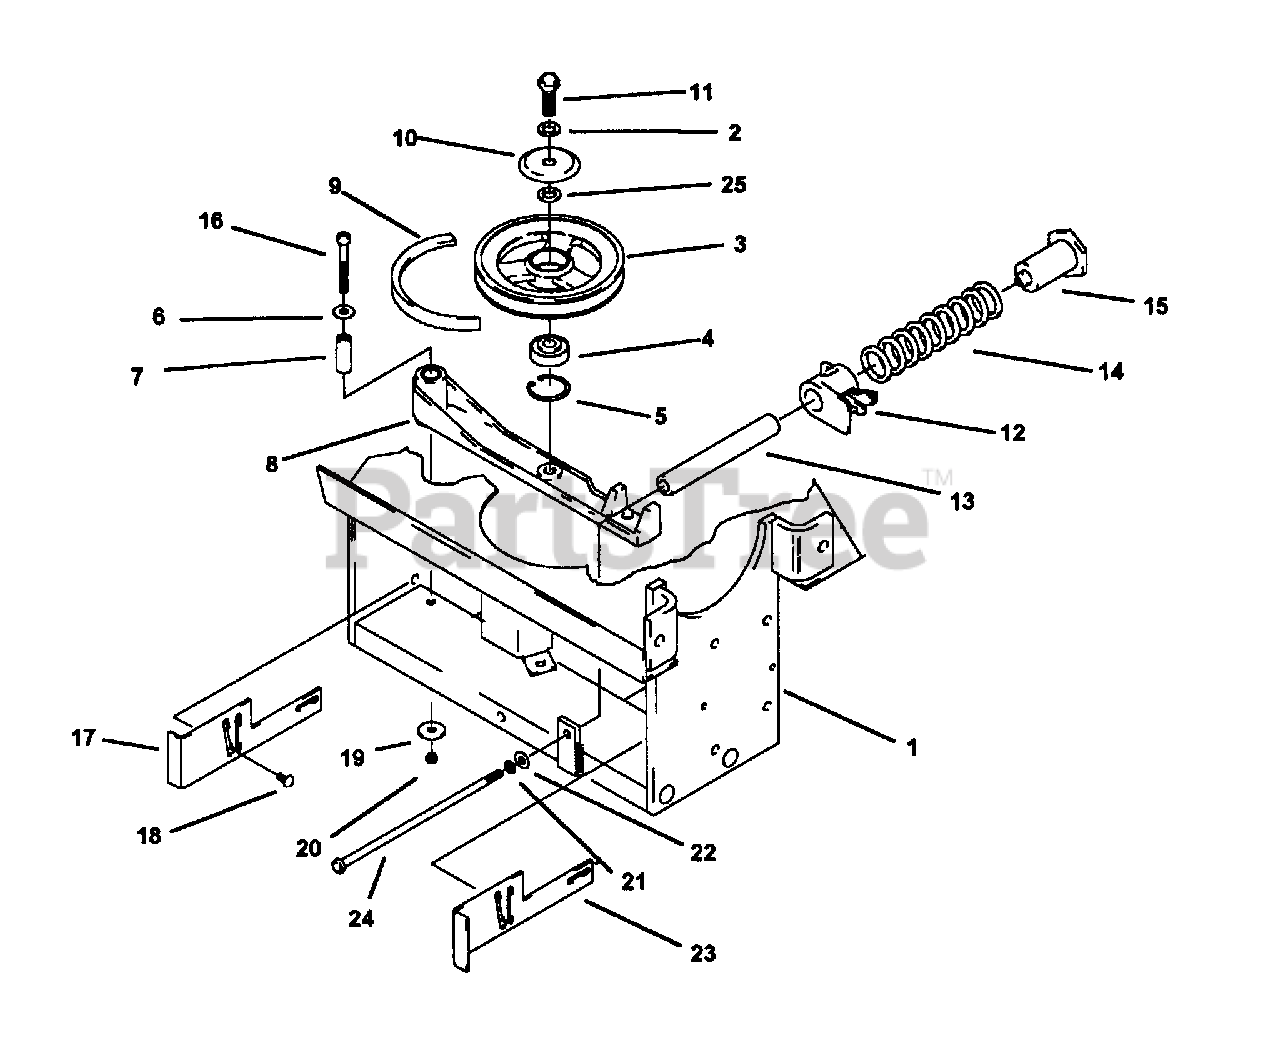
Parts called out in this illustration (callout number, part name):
2	LOCKWASHER, 1/2" STD. SPLIT SPRING
4	BEARING,WIDE INTER-RACE
5	SNAP RING, INTERNAL 40mm BORE
6	WASHER, FLAT, STD. 5/16
7	MOUNTING PIN
8	IDLER ARM
9	BELT, A-80 KEVLAR, MAIN DRIVE BELT
10	WASHER, BEARING CAP
12	TAIL STOP
13	CLAMP SHAFT
14	SPRING, COMPRESSION 1.359 O.D
15	TAKE UP END
16	CAPSCREW, SOCKET HEAD 5/16"-18 X 2 1/4, GR 8
17	FREEWHEEL BAR R.H.
18	DRIVE STUD, 1/4" X 1/2" LONG
20	LOCKNUT, 5/16-18 STOVER
21	LOCK WASHER, 3/8" HEAVY SPRING
22	WASHER, FLAT STD 3/8
23	FREEWHEEL BAR, L.H
24	CAPSCREW, 3/8"-16 X 9 3/4 LONG
25	WASHER, 1/2 TYPE B NARROW
